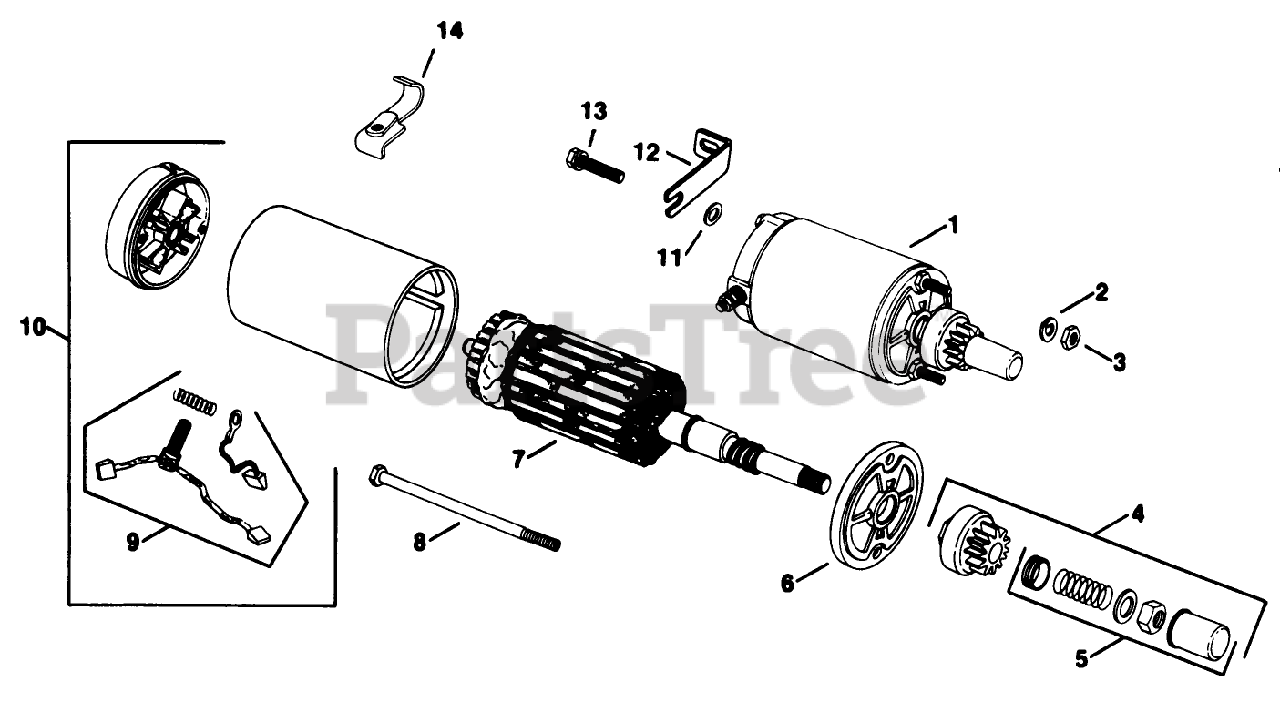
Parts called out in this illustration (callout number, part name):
1	Starter Assy. (Incl. Ref. #4-10)
2	Washer
4	Kit-Drive
5	Kit-Drive Parts
6	Cap-Drive End
7	Armature
9	Kit-Brush
10	Kit-Commutator End Cap
11	Washer
12	Bracket-Starter Support
13	Screw-H.C
14	Bracket-Mounting
